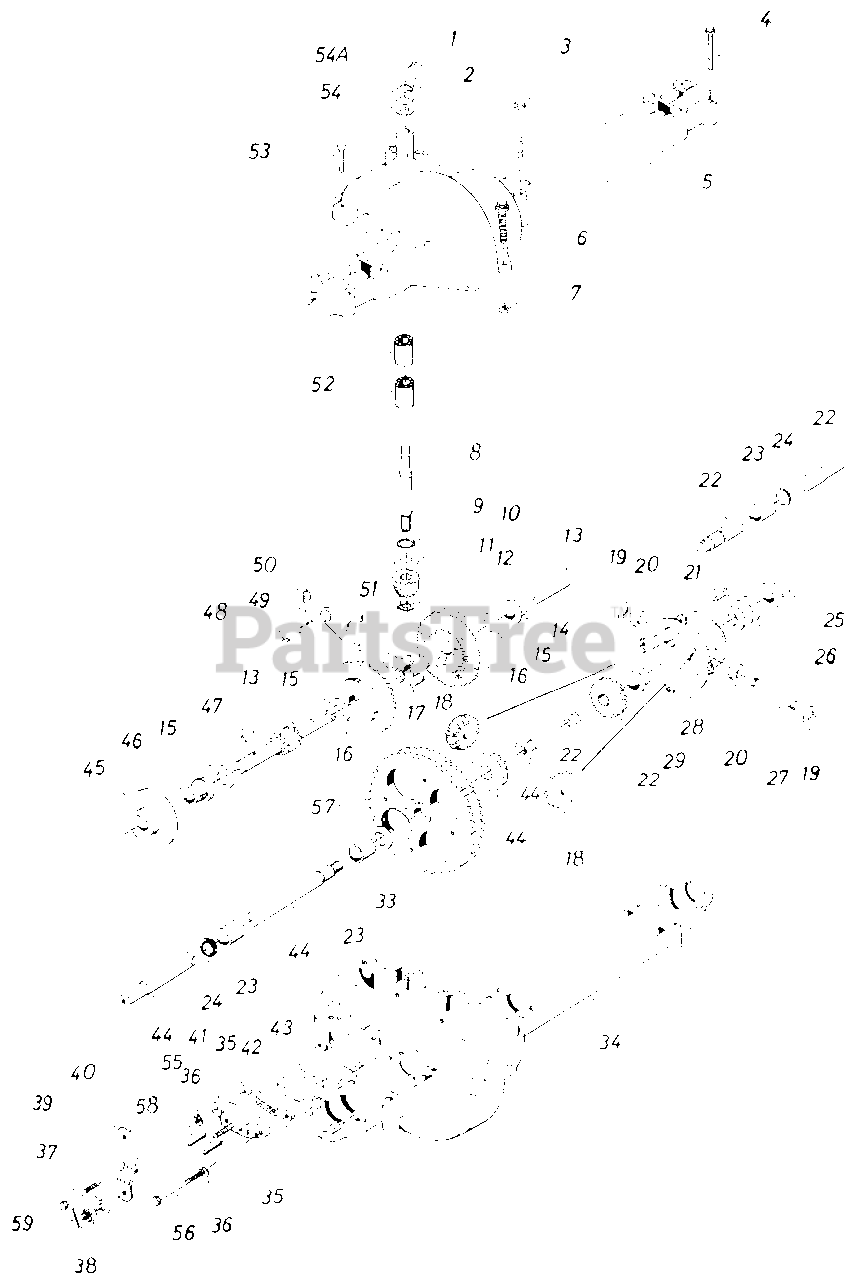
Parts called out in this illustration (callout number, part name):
1	#4 Hi-Pro Key 3/32 x 518" Dia.
2	Snap Ring .625" Shaft
3	Hex Bolt 1/4-20 x 1.75" Lg.
4	Hex Bolt 5/16-18 x 2.5"
5	Upper Housing
6	Hex Fl-Bolt 1/4-20 x .88" Lg.
7	Hex Nut 1/4-20 Thd.*
8	Input Shaft
9	Square Seal 5/8" I.D.
10	Thrust Washer 5/8" I.D. x 1.25 O.D
11	Pinion Input 14T
12	Retaining Ring 7/16" Ext.
13	Drive Shaft
14	Flange Brg. 5/8" I.D. x 3/4" Lg.*
15	Fl-Wash.
16	Bevel Gear 42T
17	Clutch Collar
18	Miter Gear 15T (H.D.)
19	Snap Ring
20	Thrust Bearing 1/2" I.D. x 1.0" 0. D.
21	Pan Head Scr. 1/4-20 x .50" Lg. w/Patch
22	Axle R.H. Ass'y.-Kit
23	Sleeve Bearing 3/4" I.D. x 1.0" Lg.
24	Oil Seal 3/4" I.D.
25	Flange Bearing 3/4" I.D. x 15/16" Lg.
26	Fl-Wash. .760" I.D. x 1.49" O.D.
27	Cross Shaft
28	Differential Housing Ass'y.
33	Fl-Wash. .760" I.D. x 1.49" O.D.
34	Lower Housing
35	Spacer .53" O.D. x 3/8" Lg.
36	L-Wash. 1/4" I.D.
37	Hex Bolt 1/4-20 x 1.50" Lg.(Grade 5)
38	Castle Nut 5/16-24 Thd.
39	Fl-Wash. .344" I.D. x .875" O.D.
40	Actuating Arm
41	Brake Yoke
42	Puck Plate
43	Brake Puck
44	Axle L.H. Ass'y.-Kit
45	Brake Disc
46	Flange Bearing 5/8" I.D. x 15/16" Lg.
47	Woodruff Key 3/16 x 5/8 HT
48	Shift Fork Ass'y.
49	Ball Detent .250" Dia.
50	Spring Detent
51	#9 Hi-Pro Key 3/16" x 3/4" Dia. HT
52	Needle Brg. 5/8" I.D. x '/2" Lg.
53	Hex Bolt 1/4-20 x 1.00" Lg.
54	Fl-Wash. 5/8" I.D. x .030
54A	Fl-Wash. 5/8" I.D. x .040
55	Actuating Pin 5/16" Dia.
56	Hex Bolt 1/4-20 x 2.50" Lg.(Grade 5)
57	Differential Gear 72T Ass'y. w/ Bearing
58	Sq. Hd. Bolt 5/16-24 Thd.
59	Cotter Pin 3/32" Dia. x .50" Lg.
